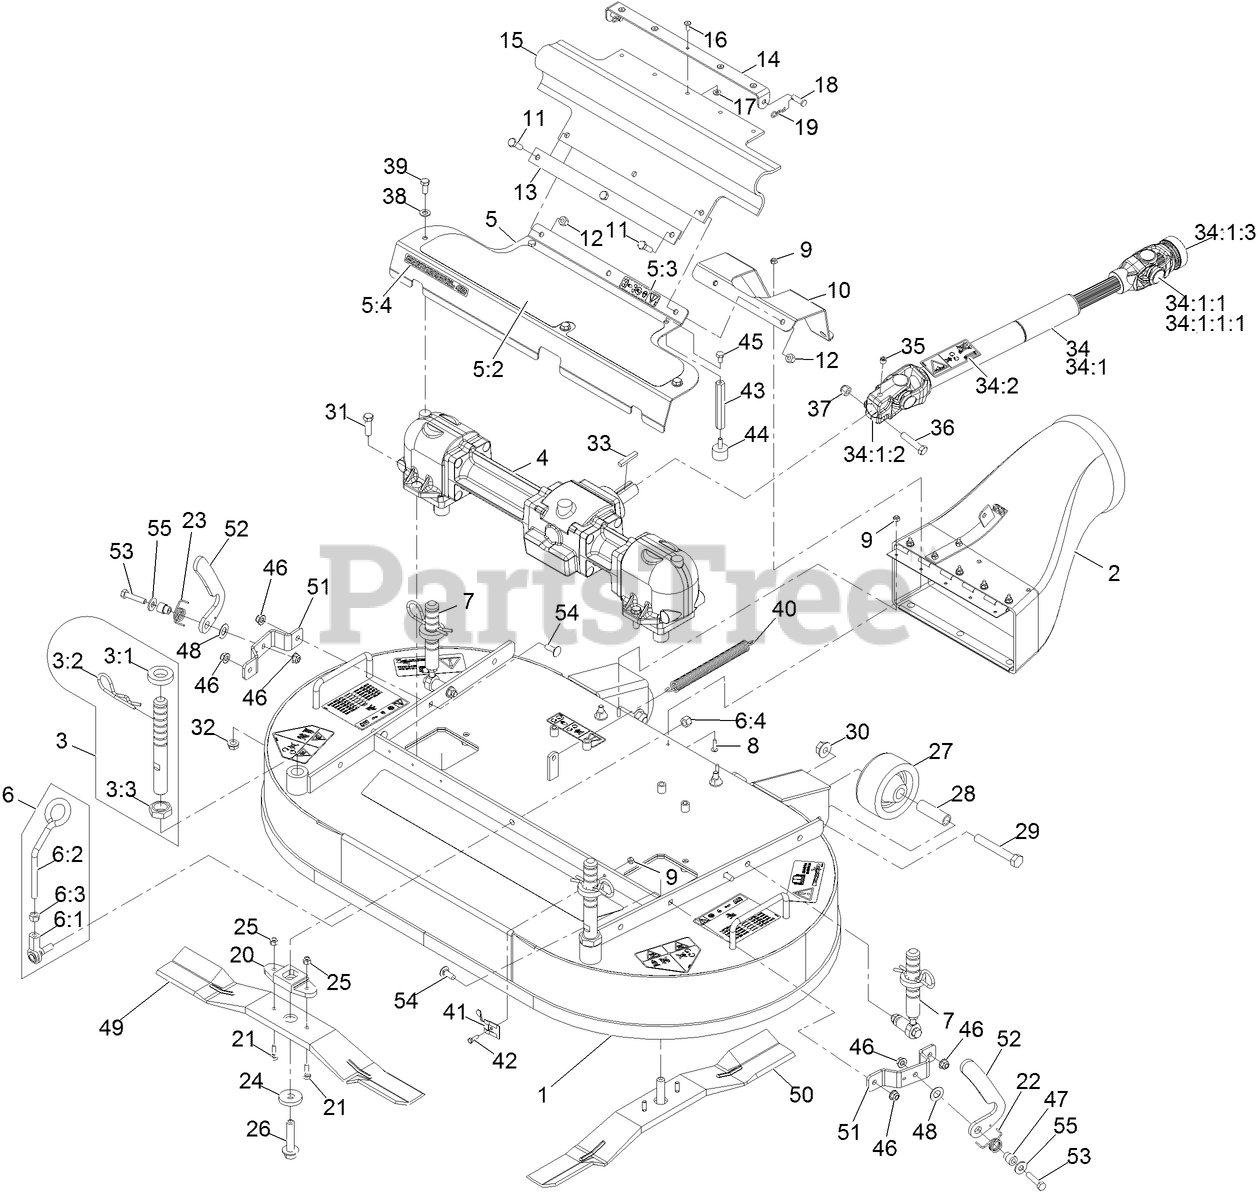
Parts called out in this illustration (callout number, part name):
1	Deck-Cutting 42 W/Decals
2	DISCHARGE TUBE ASM
3	FRONT DECK HEIGHT ADJUST
3:1	SPACER-DECK SUPPORT
3:2	PIN-CUT HEIGHT
3:3	NUT-JAM
4	GEARBOX ASM
5	ASM,GEARBOX COVER 42 W/DECAL
5:2	PAD-ANTI SKID
5:3	DECAL-DANGER
5:4	Decal-Commercial 42
6	DECK LATCH ASM
6:1	BALLJOINT-RH
6:2	LATCH-DECK
6:3	NUT-HEX
6:4	NUT-LOCK
7	REAR DECK HEIGHT ADJUST A
8	SCREW-HEAD, TRUSS
9	NUT-LOCK, NI
10	GUARD-DRIVE SHAFT
11	SCREW-HH
12	NUT-LOCK, NI
13	STRAP-DRIVE, LINE COVER
14	BRACKET-GUARD, PTO
15	GUARD-PTO
16	RIVET-BLIND
17	WASHER-FLAT
18	PIN-CLEVIS
19	PIN-COTTER
20	DRIVER-BLADE
21	BOLT-SHEAR
22	SPRING-TORSION, LH (YELLOW)
23	Spring-Torsion, RH
25	NUT-LOCK, NI
26	BOLT-BLADE
27	ROLLER-DECK
28	SPACER-ROLLER
29	SCREW-HH
30	NUT-HHF
31	SCREW-HH
32	NUT-HHF, WHIZ
33	KEY-SQUARE
34	DRIVE SHAFT ASM
34:1	Drive Shaft-Telescoping
34:1:1	U-JOINT KIT
34:1:1:1	FITTING-GREASE
34:1:2	YOKE-KEYED
34:1:3	YOKE-QUICK DISCONNECT
34:2	DECAL-DANGER, DRIVELINE
35	SCREW-SET, HSH
36	SCREW-HH
37	NUT-LOCK, NI
38	WASHER-PLAIN
39	SCREW-HH
40	SPRING-EXTENSION
41	CLIP-DECK, HOLD UP ROD
43	STAND-OFF
45	SCREW-HH
46	NUT-HF, NI
47	COLLAR-BASKET
48	Washer-Plastic
49	BLADE,22 INCH RH
50	BLADE,22 INCH LH
51	Bracket-Latch Pivot
52	Latch - Deck
53	SCREW-HH
54	BOLT-CARR
55	WASHER-FLAT
